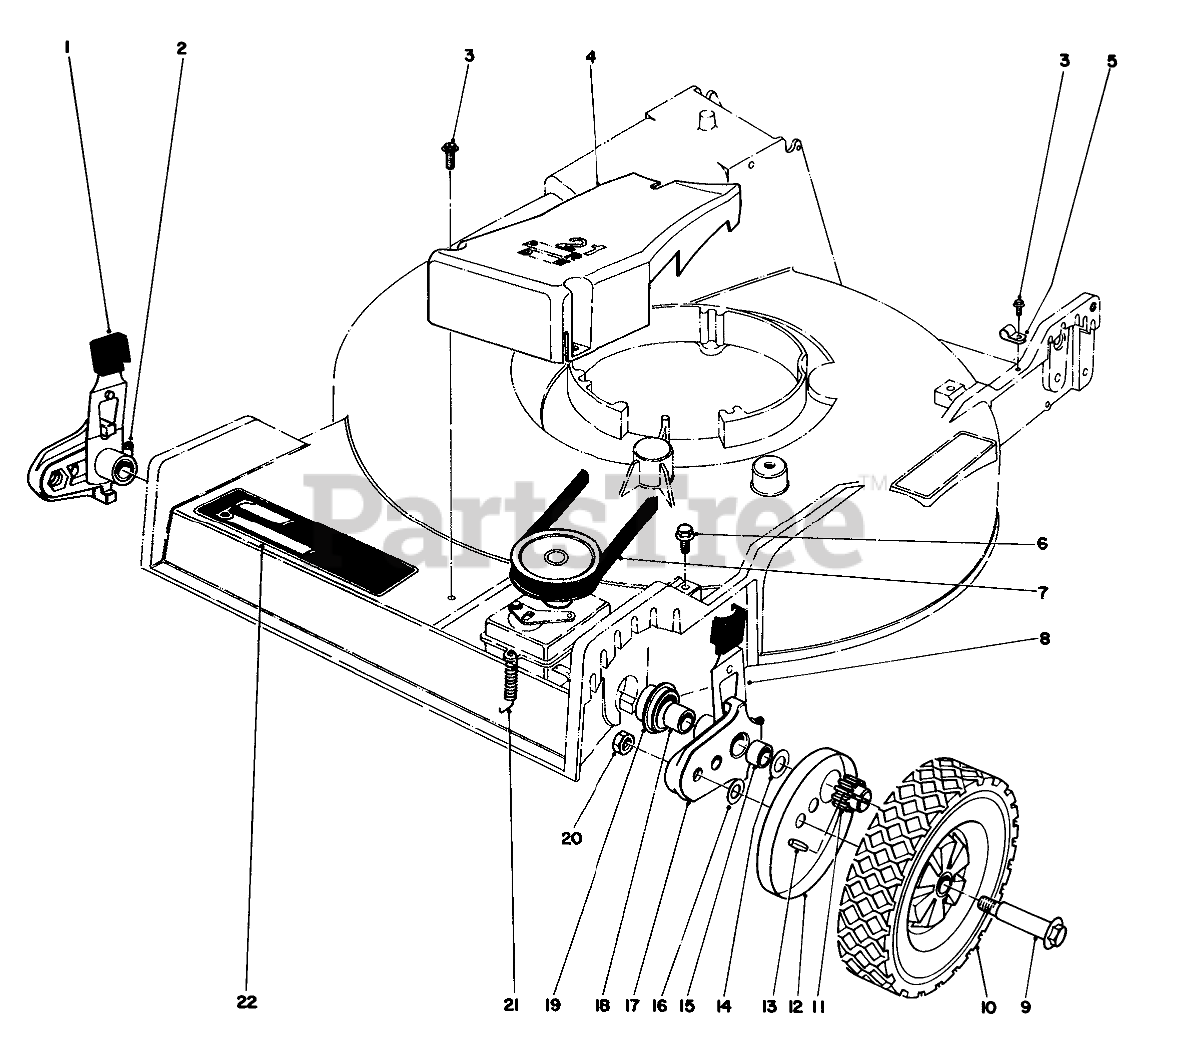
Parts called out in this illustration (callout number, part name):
1	KNOB-ARM
2	FITTING-GREASE
3	SCREW
4	Belt Cover
5	CLAMP-NYLON
6	SCREW-HWHTF
7	V BELT
8	SPRING ARM ASM SP
9	BOLT-WHEEL
10	Wheel & Tire Assembly
11	Pinion Gear
12	Cover-Wheel
13	Pin
14	WASHER-THRUST
15	Bushing
16	WASHER
17	Pivot Arm Assembly (Incl. Ref. #2, 15 & 18)
18	Bushing
19	END CAP
20	Nut
21	TENSION SPRING
22	Decal-Deck
